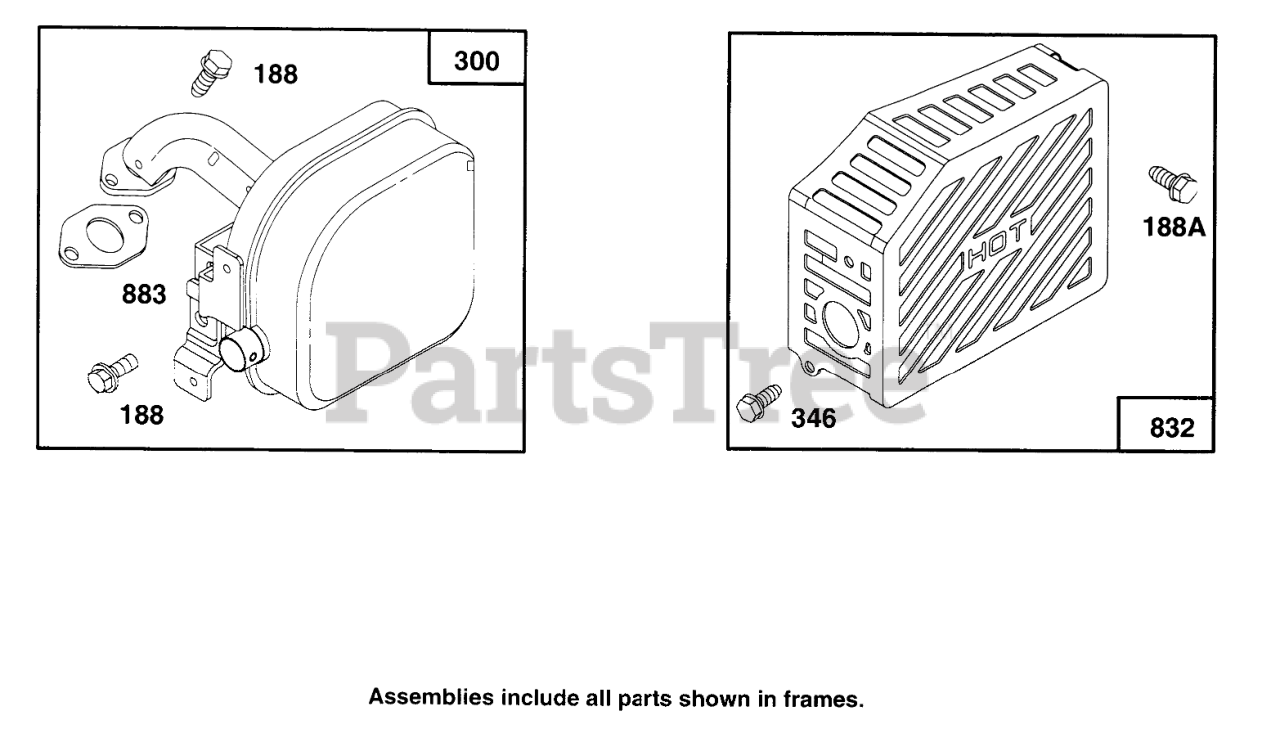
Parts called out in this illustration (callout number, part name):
188	SCREW - HEX HEAD
188A	SCREW - SEM
300	MUFFLER - EXHAUST
346	SCREW - SELF-TAPPING
832	Guard-Muffler
883	EXHAUST GASKET
